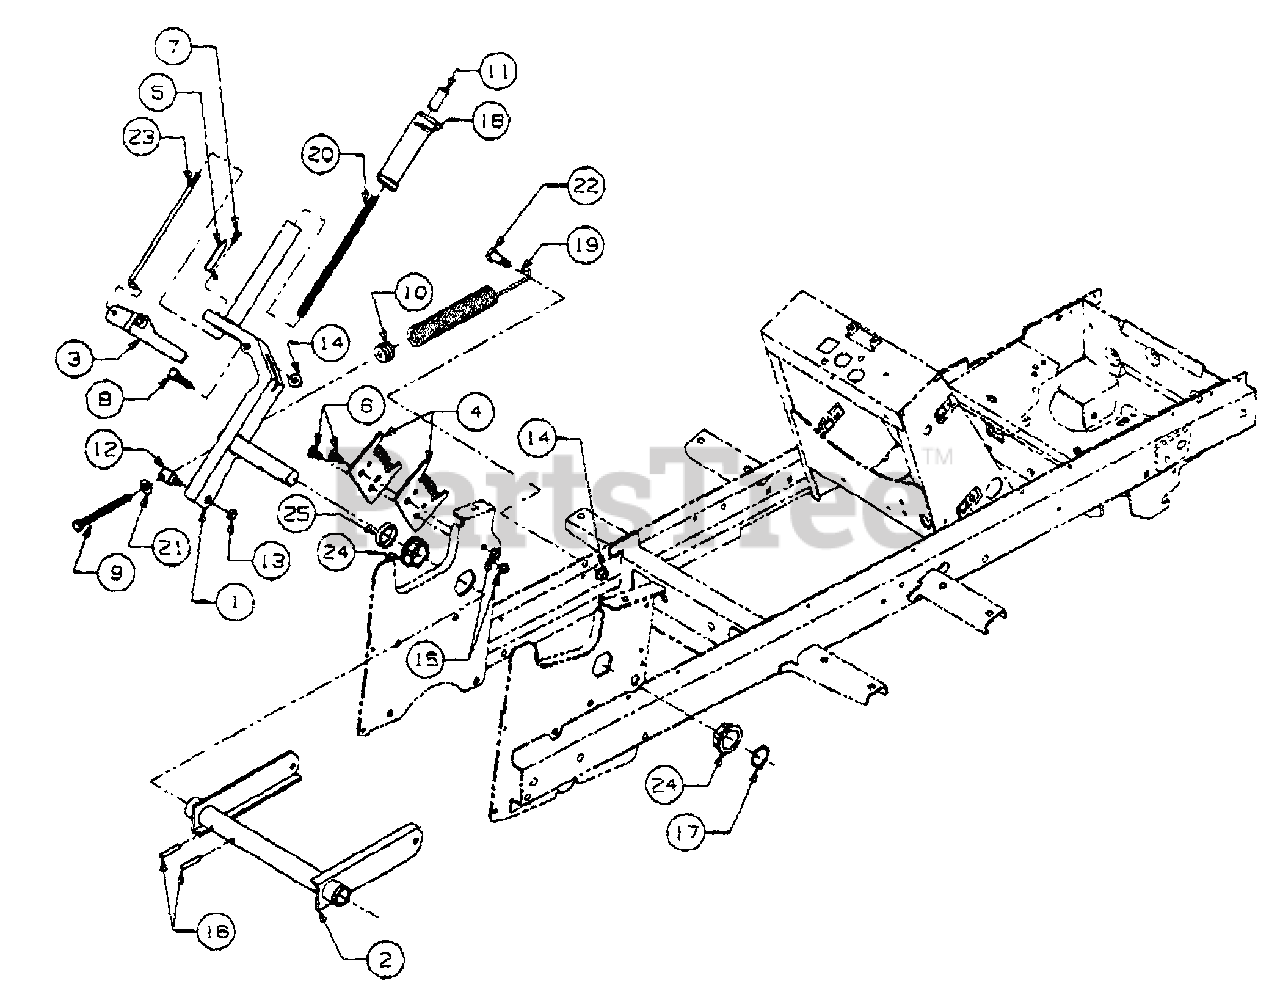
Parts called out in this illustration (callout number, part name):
3	Fork, Lift
4	Bracket, Lift Index
5	Indicator, Lift Height
6	Bolt, Carriage, 5/16-18 x .75 Lg
7	Screw, Hex Wash Tapp, 1/4 x .50 Lg
8	Screw, Hex Cap, 34-18 x 2.0 Lg GR5
9	Screw, Hex Cap, 30-18 x 4.25 Lg GR5
10	Insert, Spring
11	Button, Handle
12	Ferrule, Adjustment
13	Nut, Hex Center Lock, Jam, 3/8-24
14	Nut, Hex Flanged Lock, 34-16
15	Nut, Hex Flanged Top Lock, 5/16-18
16	Pin, Spiral Spring, 1/4 Dia x 1.50 Lg
17	Ring, Snap, 1.25 Dia Shaft
18	Grip, Lift Handle
19	Spring, Extension
20	Spring, Compression
21	Washer, Flat, .385 x .87 x .06 Thk
22	Bolt, Shoulder
23	Rod, Index
24	Bearing, Hex Flange. 1.25 ID
25	Spacer, 1.28 ID x 1.5 OD x .335 Lg
